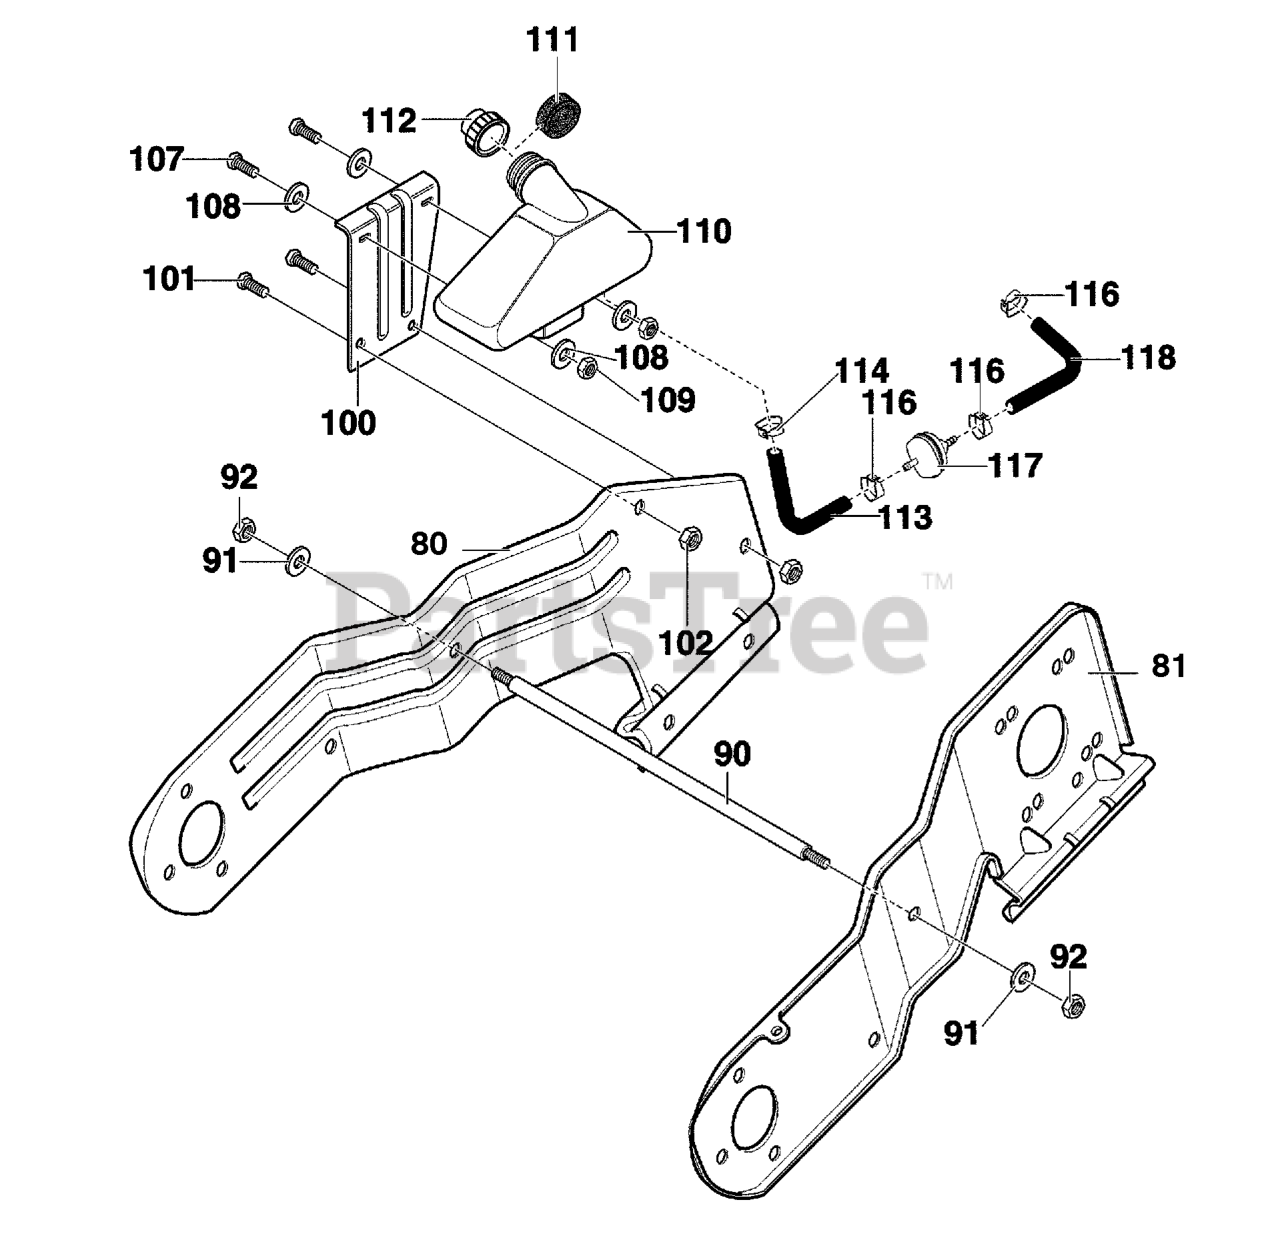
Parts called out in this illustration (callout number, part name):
80	FRAME, SIDE SUPT STEEL RH
81	FRAME, SIDE SUPT STEEL LH
90	ROD, SUPPORT
91	WASHER, HVSPTLK
92	NUT, 3/8-16 REGHEX
100	BRACKET, GAS TANK
101	SCREW, 1/4-20X.75
102	NUT, 1/4-20 REGHEXCTRLK
107	SCREW, 1/4-20X.75
108	WASHER, FLAT
109	NUT, 1/420 REGHEXCTRLK
110	TANK, FUEL
111	RING, FOAM FUEL TANK
112	CAP, GAS
113	TUBING 8 IN.
114	CLAMP, HOSE SCREW
116	CLAMP, HOSE
117	FILTER IN LINE
118	TUBING, 6 IN.
